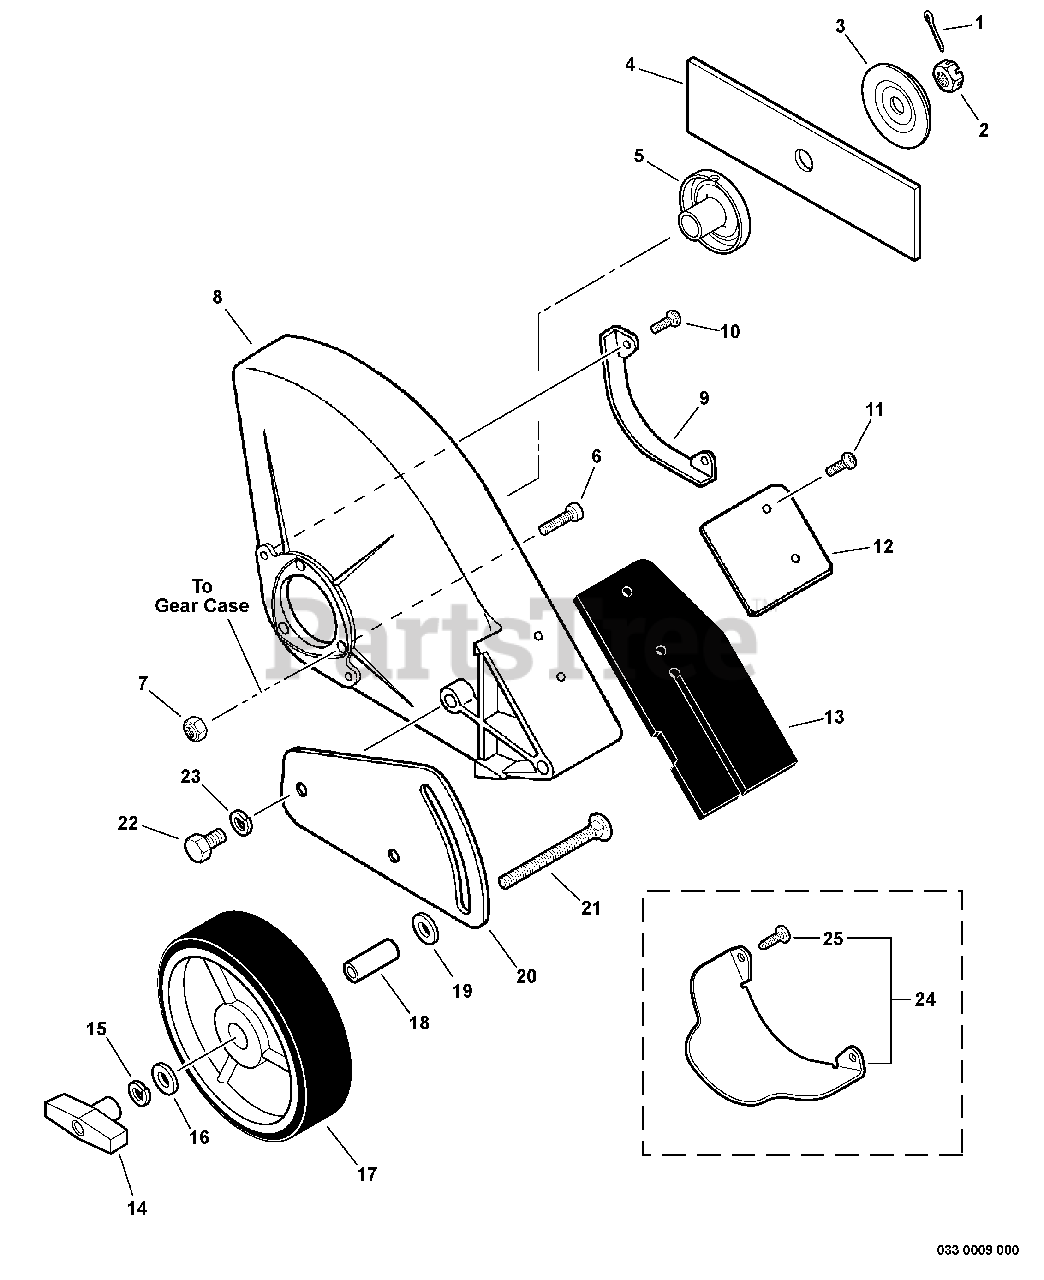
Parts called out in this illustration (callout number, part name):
1	PIN, COTTER 2×22
2	NUT 10×1.25 LH
3	PLATE, ADAPTOR - LOWER
4	BLADE - 2 PK
5	PLATE, ADAPTOR - UPPER
6	BOLT, TORX 5×20
7	NUT, LOCK M5
8	SHIELD, BLADE
9	GUARD, SHIELD
10	BOLT, TORX 4×12
11	BOLT, TORX 4×12
12	PLATE, FLAP
13	FLAP, DEBRIS
14	KNOB, FASTENER
15	WASHER, SPRING 8
17	WHEEL
18	COLLAR 12
19	WASHER, SPRING 10
20	BRACKET, WHEEL
21	BOLT 5/16"-18×2-1/2"
22	BOLT 8×14
23	WASHER, SPRING 8
24	GUARD KIT, SHIELD
25	SCREW 4×12
